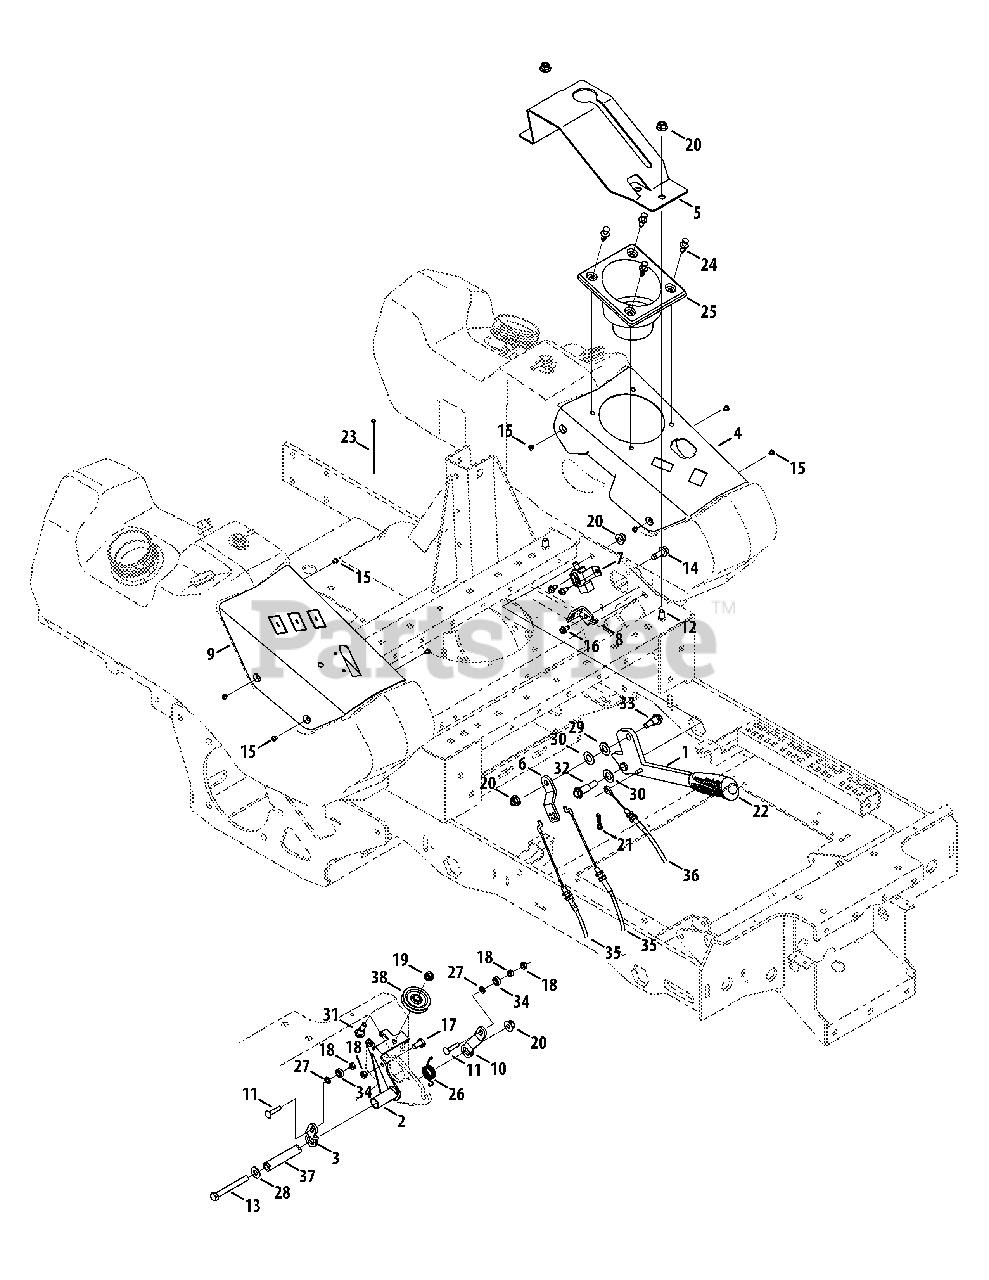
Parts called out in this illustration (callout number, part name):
1	Brake Handle Weldment
2	Brake Control Bracket Assembly
3	Lock Control Plate
4	LH Control Panel
5	Boot Brake Bracket
6	Pivot Brake Bracket
7	Brake Switch Bracket
8	Lockout Cable Mounting Bracket
9	RH Control Panel
10	Lock Control Plate
11	Screw, 1/4-20 x 1.50 GR.5
12	Carriage Bolt, 3/8-16 x .75
13	Screw, 3/8-16 x 5.0
14	Screw, 3/8-16 x 1.00
15	Machine Screw, #10-32 x .25
16	Hex Flange Screw, 1/4-20 x .500
17	Screw, 1/4-20 x 2.00
18	Nut, 1/4-20, Hexlock
19	Nut, 5/16-18, Flangelock
20	Nut, 3/8-16, Flangelock
21	Bow Tie Cotter Pin
22	Grip, .50 ID
23	Cable Tie
24	Rivet, .3125
25	Cup Holder
26	Coil Spring, .862 Dia. x .075 Wire
27	Washer, .281 x .500 x .063
28	Washer, .385 x .87 x .06
29	Washer, .510 x 1.00 x .060
30	Washer, .531 x 1.00 x .030
31	Shoulder Screw, .437 x .470, 5/16-18
32	Shoulder Bolt, .50 x .925, 3/8-16
33	Shoulder Screw, .50 x .50, 3/8-16
34	Ball Bearing, .250 x .625
35	Brake Cable
36	Brake Lockout Cable
37	Spacer, .385 x .625 x 3.293
38	Roller Cable Pulley, 1.69 Dia.
